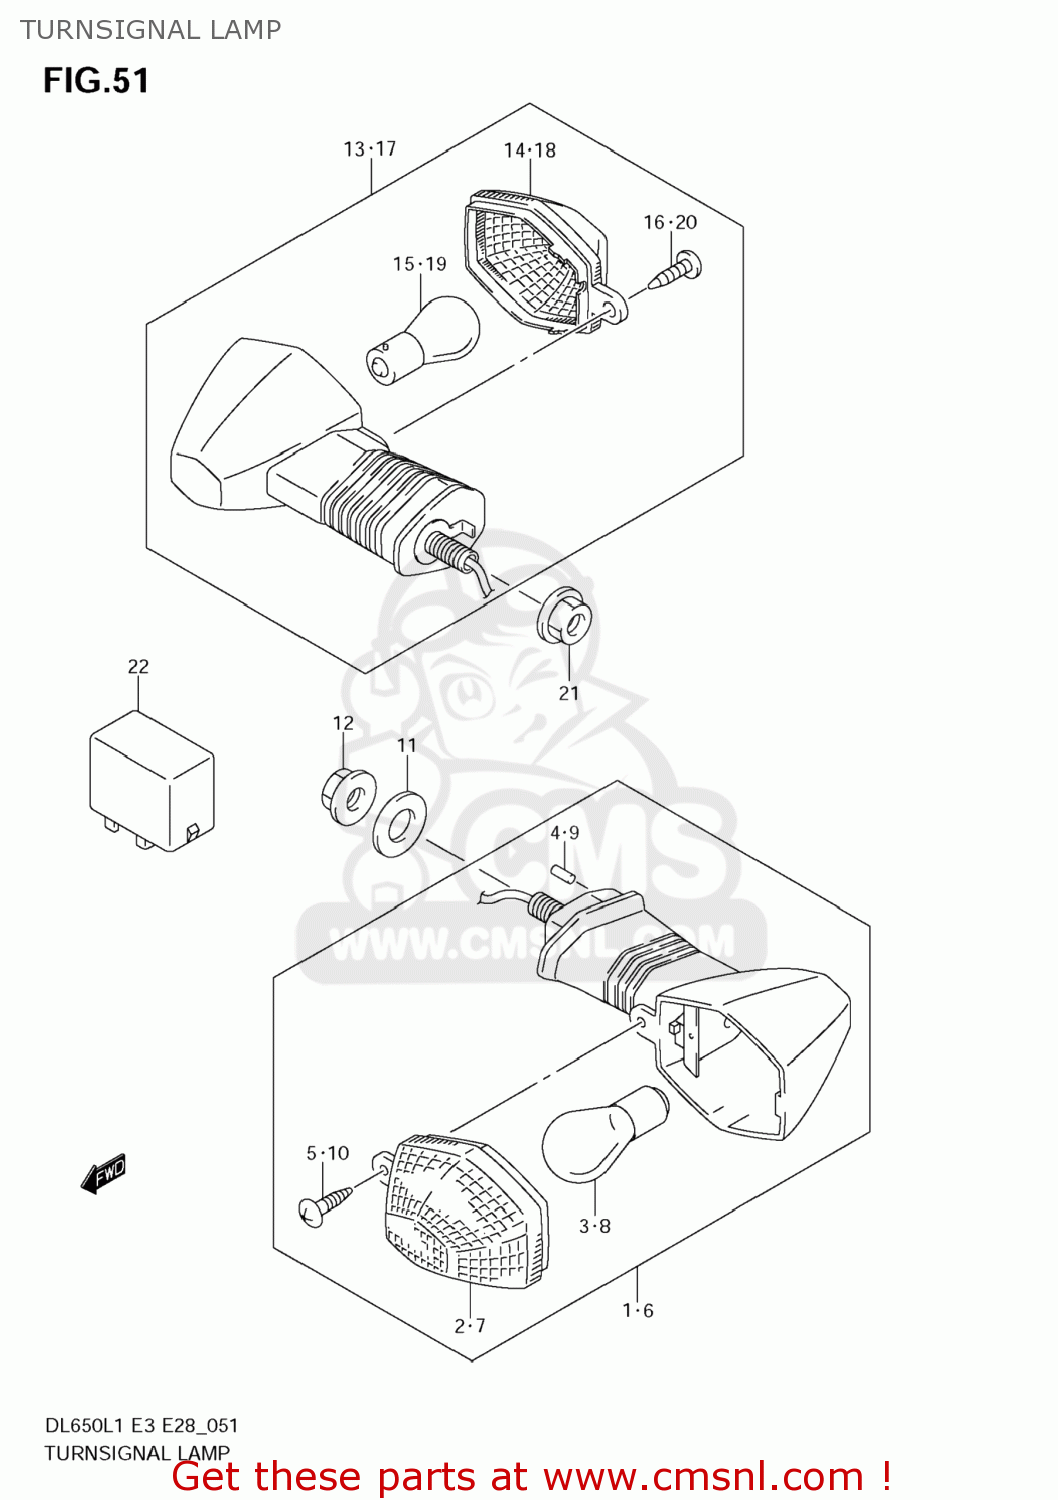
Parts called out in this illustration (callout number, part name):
1	LAMP ASSY,FR TURN SIGNAL,R
2	LENS
3	BULB(12V21W,AMBER)
4	PIN(4.5X9.5)
5	SCREW
6	LAMP ASSY,FR TURN SIGNAL,L
7	LENS
8	BULB(12V21W,AMBER)
9	PIN(4.5X9.5)
10	SCREW
11	WASHER(12.5X30X1.6)
12	NUT
13	LAMP ASSY,RR TURNSIGNAL,R
14	LAMP ASSY,RR TURNSIGNAL,L
15	LENS
16	LENS
17	BULB(12V21W,AMBER)
18	BULB(12V21W,AMBER)
19	SCREW
20	SCREW
21	NUT
22	RELAY ASSY,TURNSIGNAL LAMP
